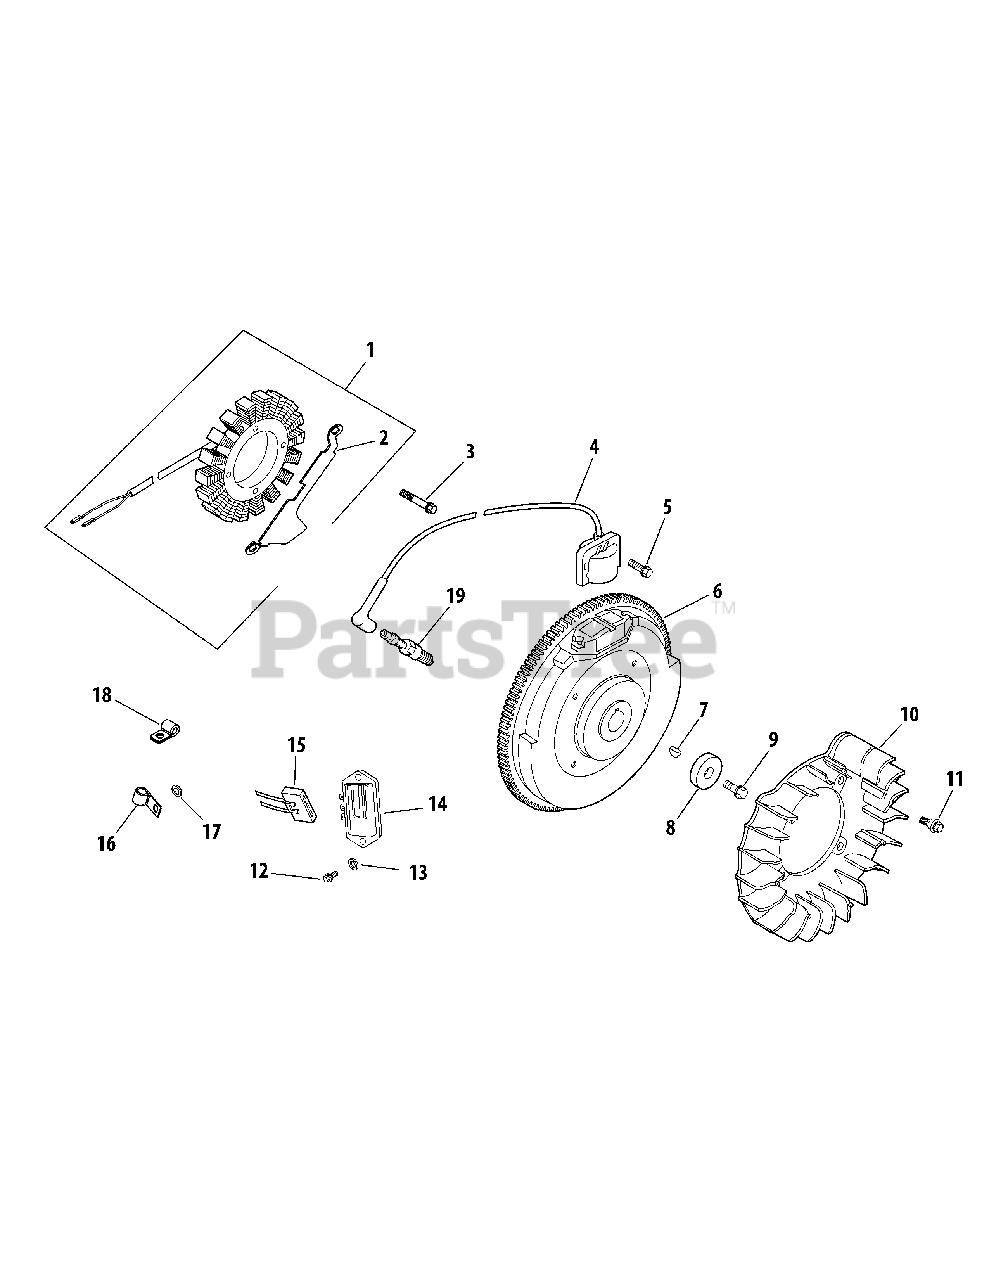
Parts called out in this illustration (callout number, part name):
1	Stator Kit, 15 Amp
2	Bracket, Stator Wire
3	Screw, Stator Mtg. M5 x .8 x 25
4	Module, Ignition
5	Screw, Module M5 x .8 x 20
6	Flywheel Assembly
8	Washer, Flat, 13/32
9	Screw, Flange M10x1.5 x 45
10	Fan
11	Bolt, Shoulder
12	Screw Phillips Hd., #11-16 x .875
13	Washer, Plain
14	Regulator - Rectifier
15	Connector, Regulator-Rectifier
16	Clip, Cable
17	Washer, Plain 1/4"
19	Spark Plug
